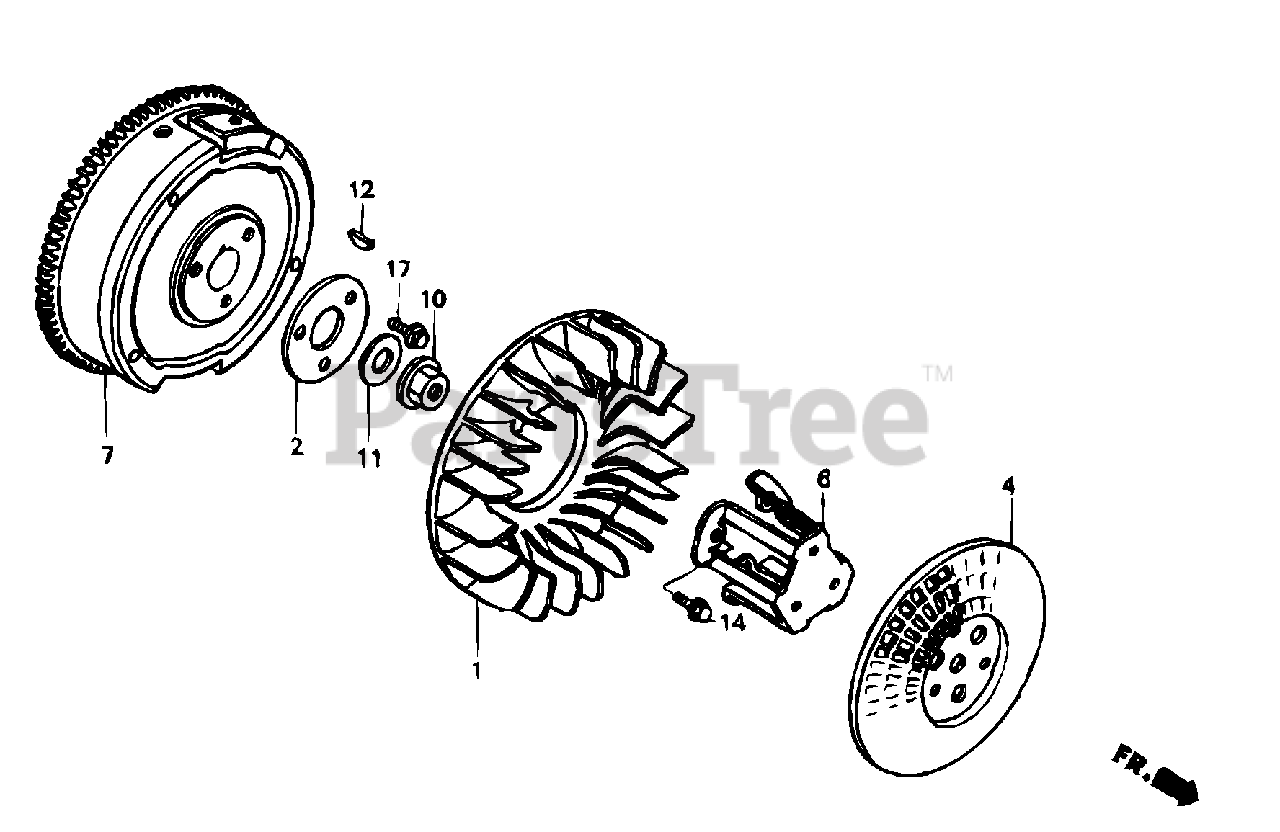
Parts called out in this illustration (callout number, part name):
1	Fan, Cooling
2	Plate, Cooling Fan Setting
4	Grid, Screen
6	Holder, Screen Grid
10	Nut, Flange (20mm)
11	Washer (20mm)
12	Key, Special Woodruff (25x18)
14	Bolt, Flange (8x16)
17	Bolt, Flange (8x16)
